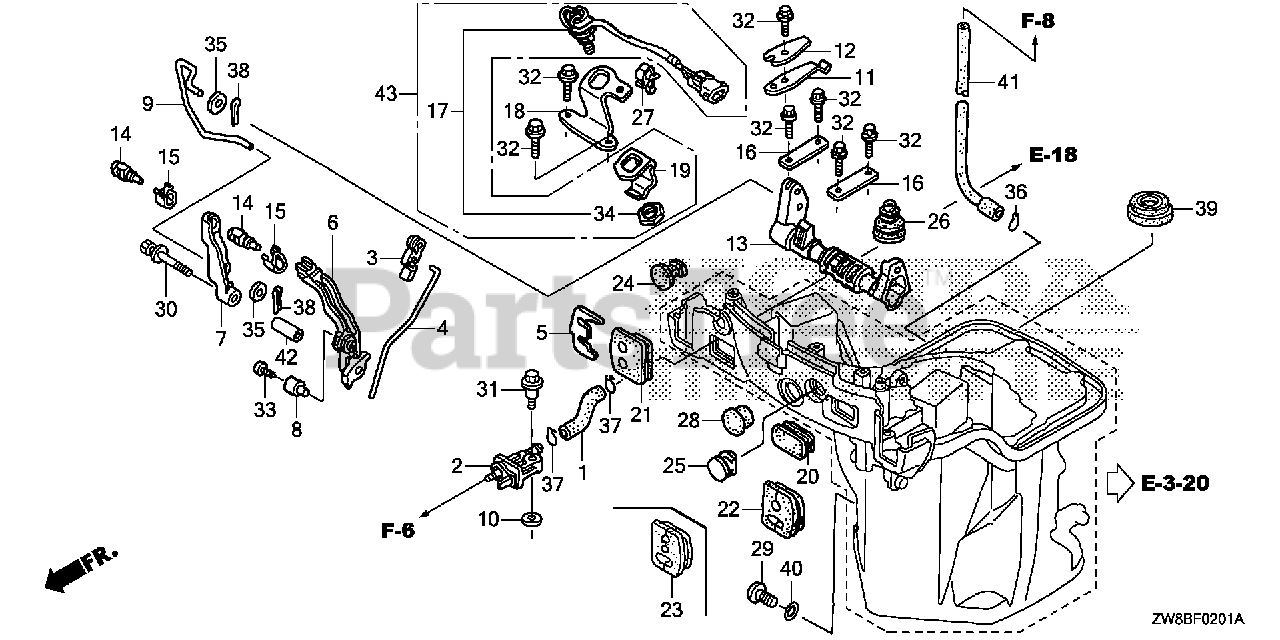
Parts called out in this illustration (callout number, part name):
1	TUBE A, FUEL
1	TUBE A, FUEL (FKM)
2	CONNECTOR ASSY., FUEL (B)
3	LINKAGE, PIVOT
4	ROD, THROTTLE
5	PLATE, REMOTE CONTROL CABLE
6	ARM, THROTTLE REMOTE
7	ARM, SHIFT LINK
8	HOLDER, THROTTLE ROD
9	ROD, SHIFT LINK
10	WASHER, PIVOT
11	SPRING, CLICK
12	SPRING, CLICK ASSIST
13	SHAFT, SHIFT
14	PIVOT, SHIFT
15	PLATE, LOCK
16	PLATE, SHIFT SHAFT
18	BRACKET, NEUTRAL SWITCH
20	GROMMET G, OIL CASE
21	GROMMET A, OIL CASE
23	GROMMET B, OIL CASE (PT)
24	GROMMET F, OIL CASE
25	GROMMET D, OIL CASE
26	GROMMET E, OIL CASE
27	CLIP, BRAKE PIPE (A)
28	CAP, HANDLE (LOWER)
29	BOLT, OIL CHECK
30	BOLT-WASHER (6X40)
31	BOLT, SPECIAL (6X22) (CT200)
32	BOLT, FLANGE (5X12) (CT200)
33	BOLT, RECESSED (5X8)
34	NUT, HEX. (20MM)
35	WASHER, PLAIN (7MM)
36	CLIP, TUBE (B10)
37	CLIP, TUBE
37	CLIP, TUBE (B12)
38	PIN, SPLIT (2.0)
39	SEAL, WATER (13X28X7) (ENGINE NO.)
40	O-RING (5.5X1.5)
41	TUBE, WATER CHECK
42	COLLAR, DISTANCE (6X11X27)
43	SWITCH SET, NEUTRAL
